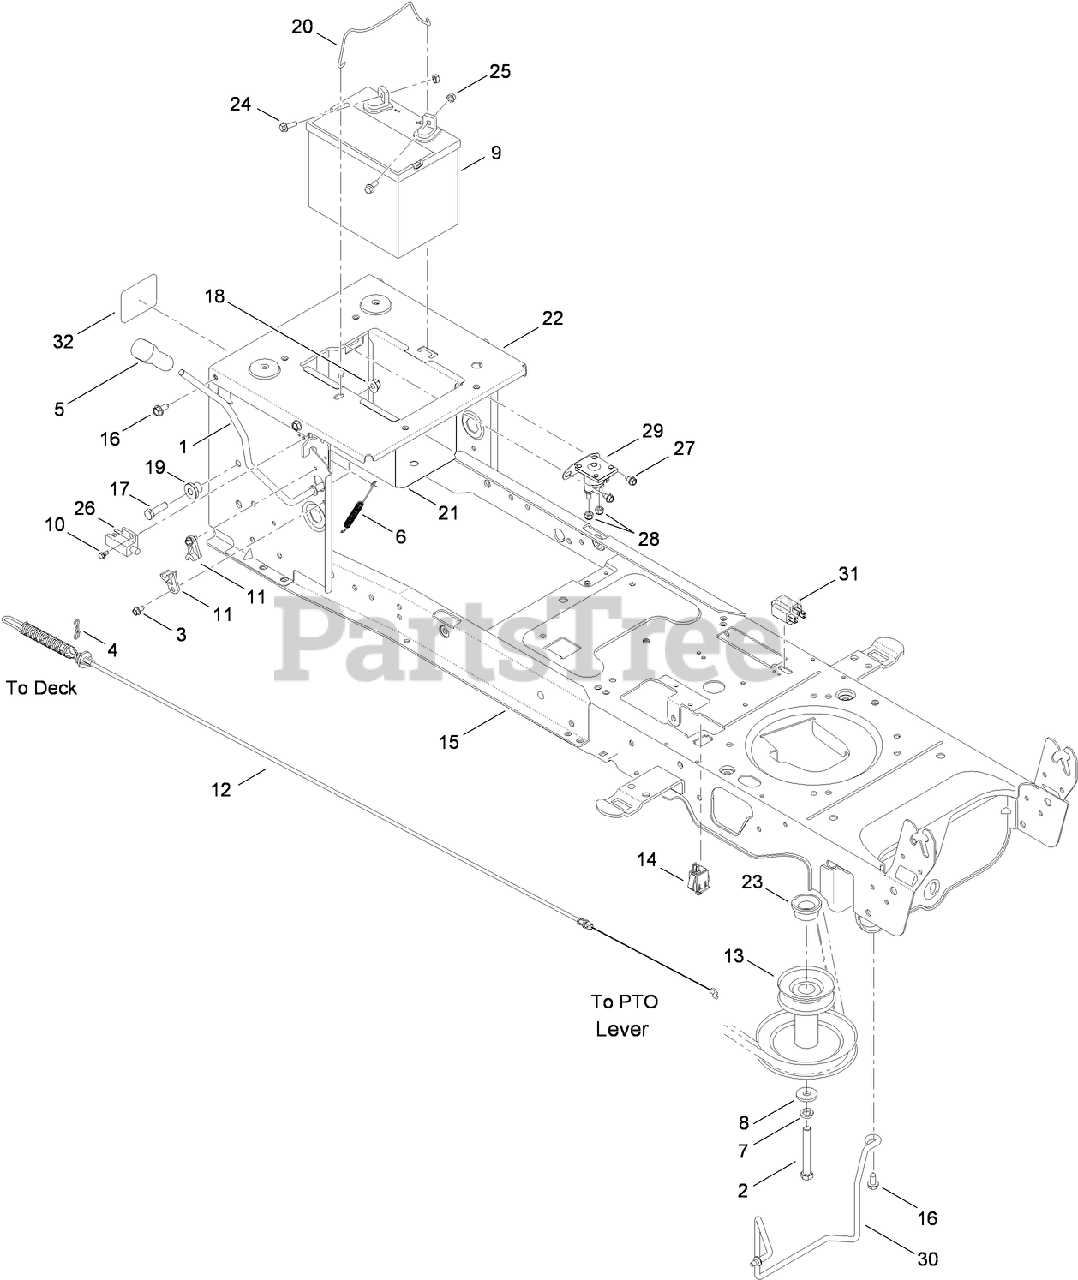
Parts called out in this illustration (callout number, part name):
1	PTO HANDLE ASM
3	SCREW-HWHTF
4	PIN-COTTER
5	GRIP-HANDLE
6	SPRING-EXTENSION
7	WASHER-LOCK
8	WASHER-FLAT
9	BATTERY-245, CCA,DRY (FLAT TOP)
10	BOLT-SHOULDER
11	BEARING-PTO
12	CABLE-ENGAGEMENT, DECK
13	PULLEY-ENGINE
14	SWITCH-PLUNGER, SNAP MOUNT
15	LOWER FRAME ASM
16	SCREW-TAP
17	SCREW-HH
18	NUT-LOCK, FLANGE
19	SPACER-SHOULDER
20	ROD-HOLDDOWN, BATTERY
21	TRAY-BATTERY
22	BRACKET-FRAME, SEAT
23	SPACER
25	NUT-SEMS
26	SWITCH-INTERLOCK, NO/NC
27	SCREW-TAP
28	NUT-LOCK, FLANGE
29	SOLENOID-12V, 2 POST 2 TAB
30	ROD-KEEPER
31	SWITCH-3 POLE
32	DECAL-RELEASE
